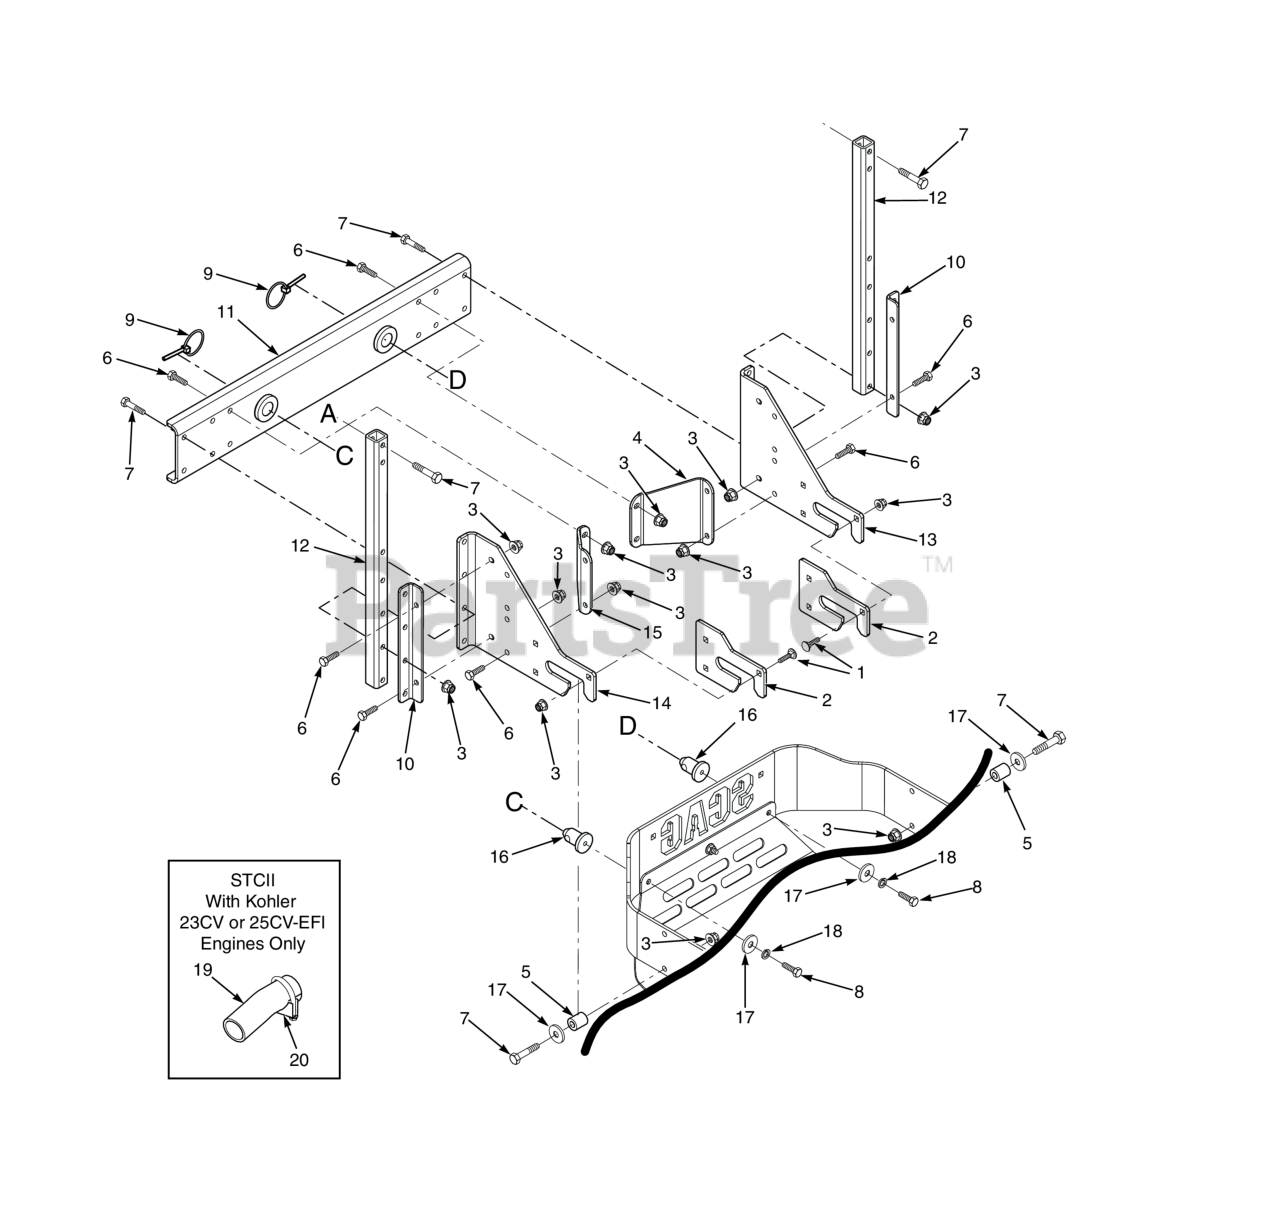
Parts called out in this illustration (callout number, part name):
1	Carriage Bolt, 3/8-16 x 1-1/4"
2	Wear Plate, GC
3	Nut, Flange Elastic Stop Nut, 3/8-16
4	Angle Bracket, GC
5	Spacer
6	Bolt, Hex Head 3/8-16 x 1"
7	Bolt, Hex Head 3/8-16 x 2-1/4" - 61"
8	Bolt, Hex Head 3/8-16 x 1-1/4" Grade 8
9	Quick Pin, 5/16" Dia.
10	Mounting Bracket, Tube
11	Mounting Bracket Weldment
12	Tube, Upright
13	Mounting Bracket, GC R.H.
14	Mounting Bracket, GC L.H.
15	Angle Bracket, GC
16	Pin, GC Locator
17	Flatwasher, 3/8-.406 x 1-1-1/2 x 7 Gauge
18	Lockwasher, 3/8" Spring, Kawasaki FX / FT & FT-EFI / B&S 32BV
19	TUBE, EXHAUST
20	Clamp, Muffler (Clamp Only)
